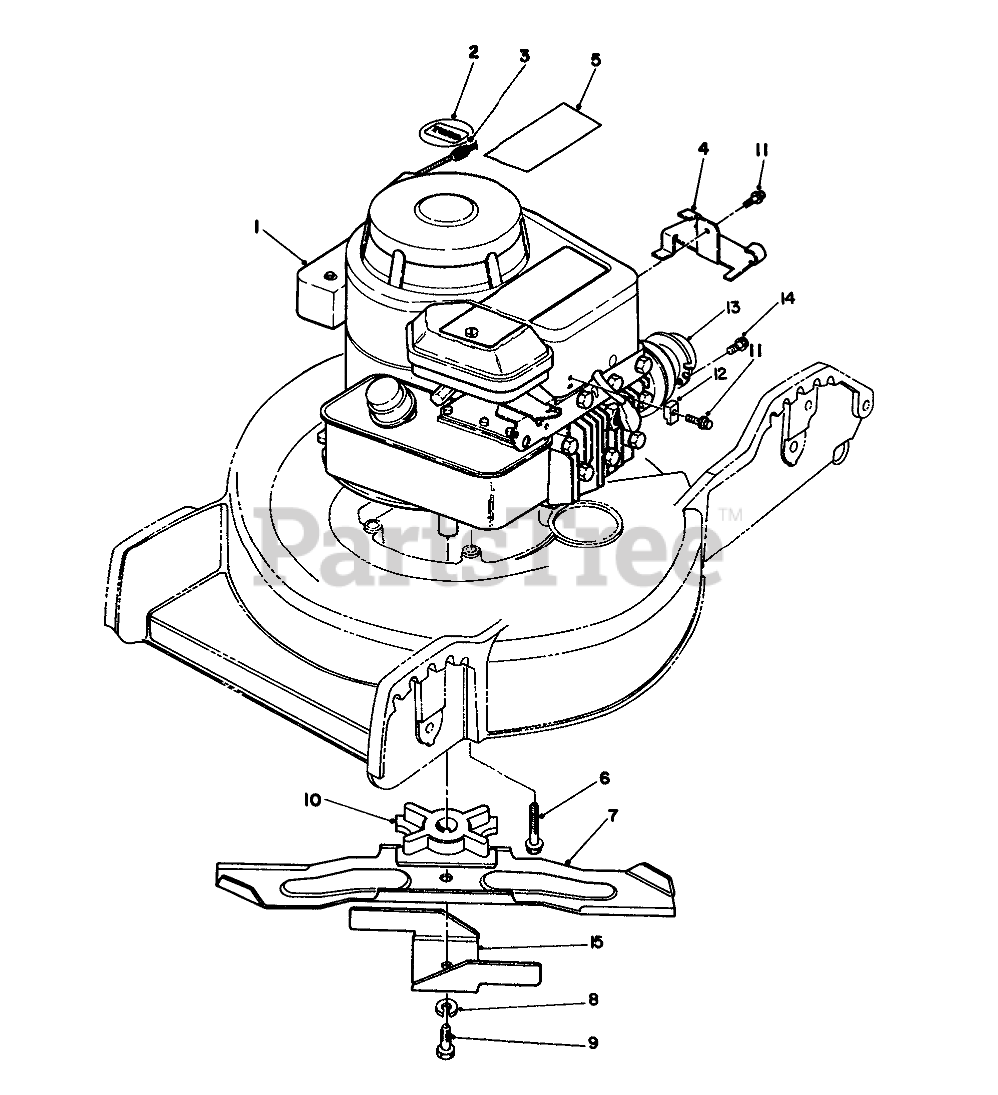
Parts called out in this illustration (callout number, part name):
2	Decal-Toro
3	STOP-ROPE
4	CABLE BRACKET
5	Decal-Engine
6	3/8-16X2 TAPTITE HEX HD
7	Blade-18"
8	WASHER-LOCK
9	SCREW-HH
10	BLADE RETAINER
11	CLAMP SCREW F/W ENGINE
12	CASING CLAMP F/W ENGINE
13	MUFFLER DEFLECTOR F/W
14	SCREW W/ENGINE
15	18 ACCELERATOR
